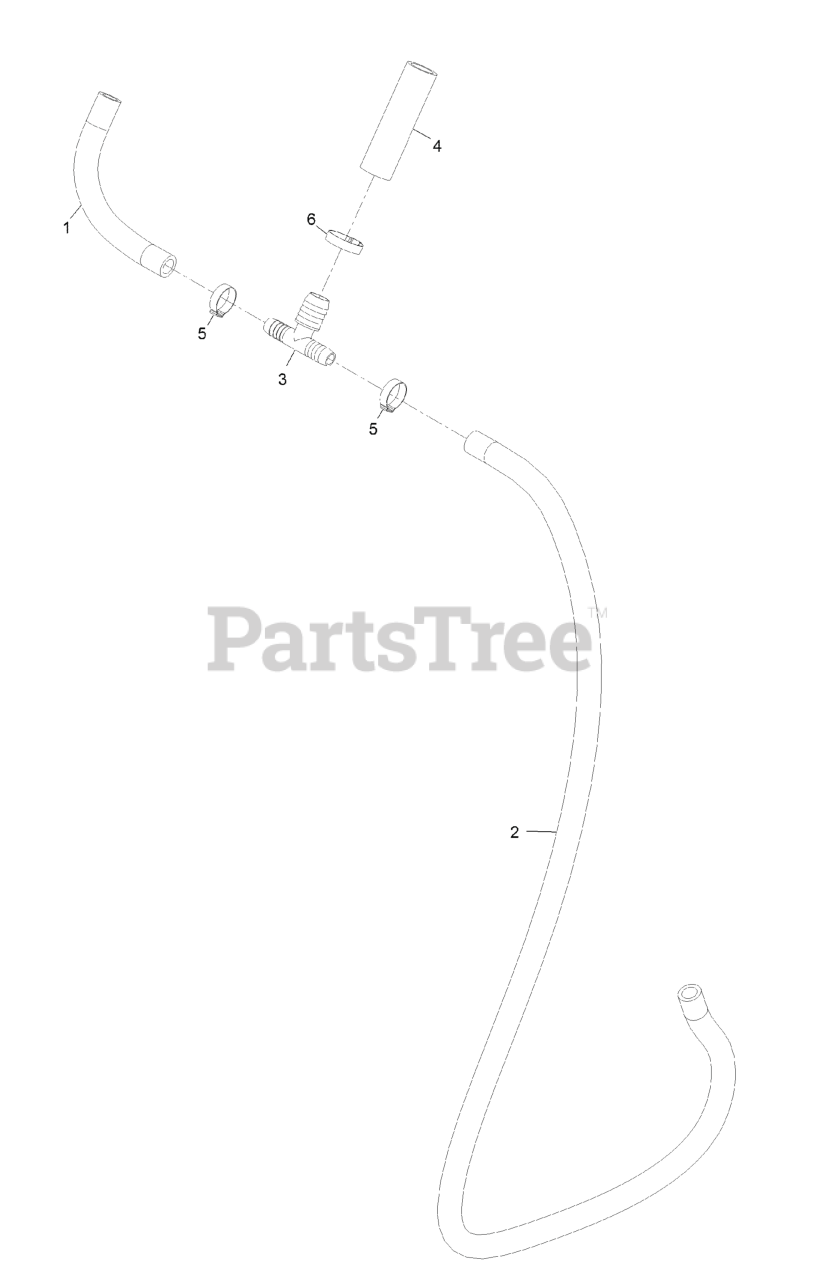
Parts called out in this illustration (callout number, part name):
1	HOSE-WATER
2	HOSE-WATER
3	FITTING-TEE
4	HOSE-WATER
